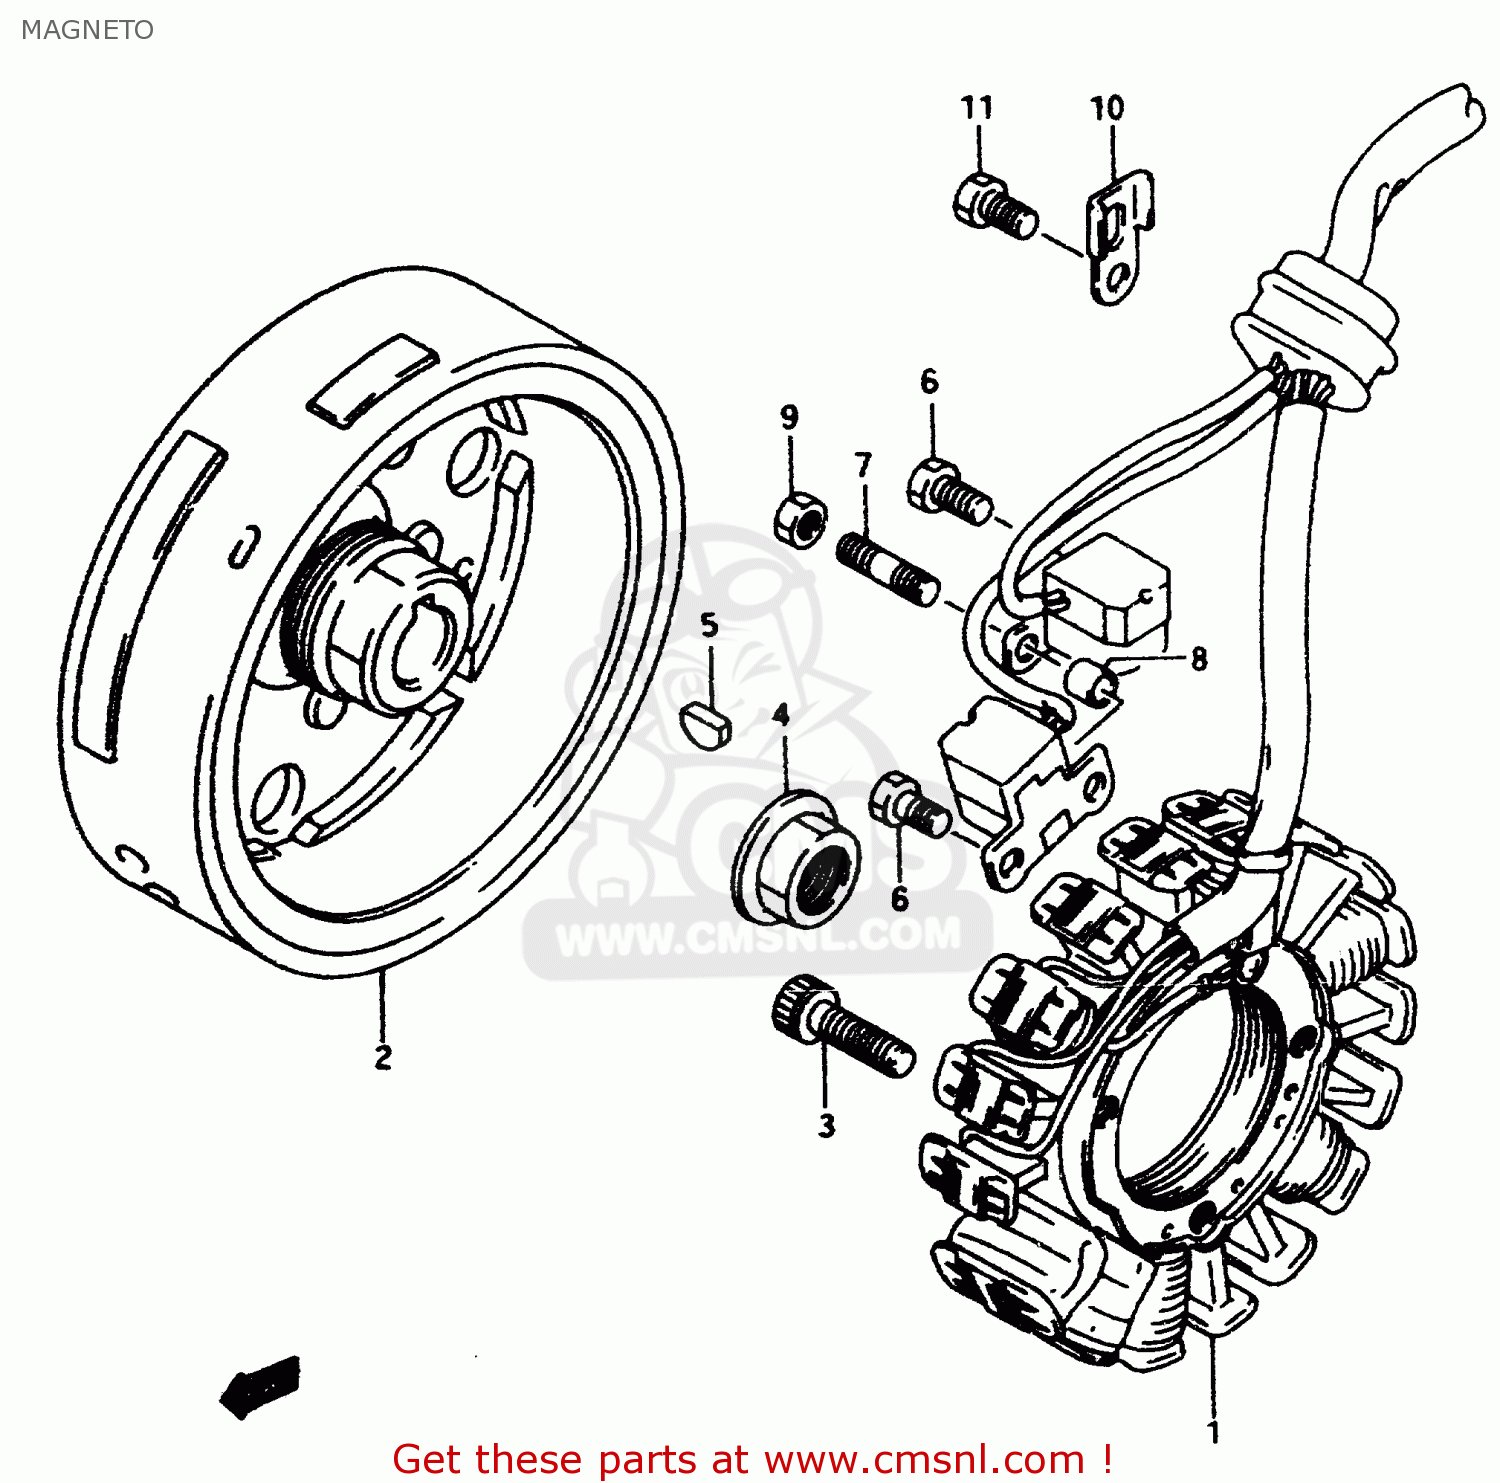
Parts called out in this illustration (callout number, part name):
1	STARTER ASSY
2	ROTOR
3	BOLT,CL.COVER
4	NUT
5	KEY
6	BOLT(5X10)
7	BOLT,STUD(5X18)
8	SPACER(5.5X9.5X6.5)
9	NUT
10	CLAMP,GENERATOR LEAD WIRE
11	BOLT(5X10)
